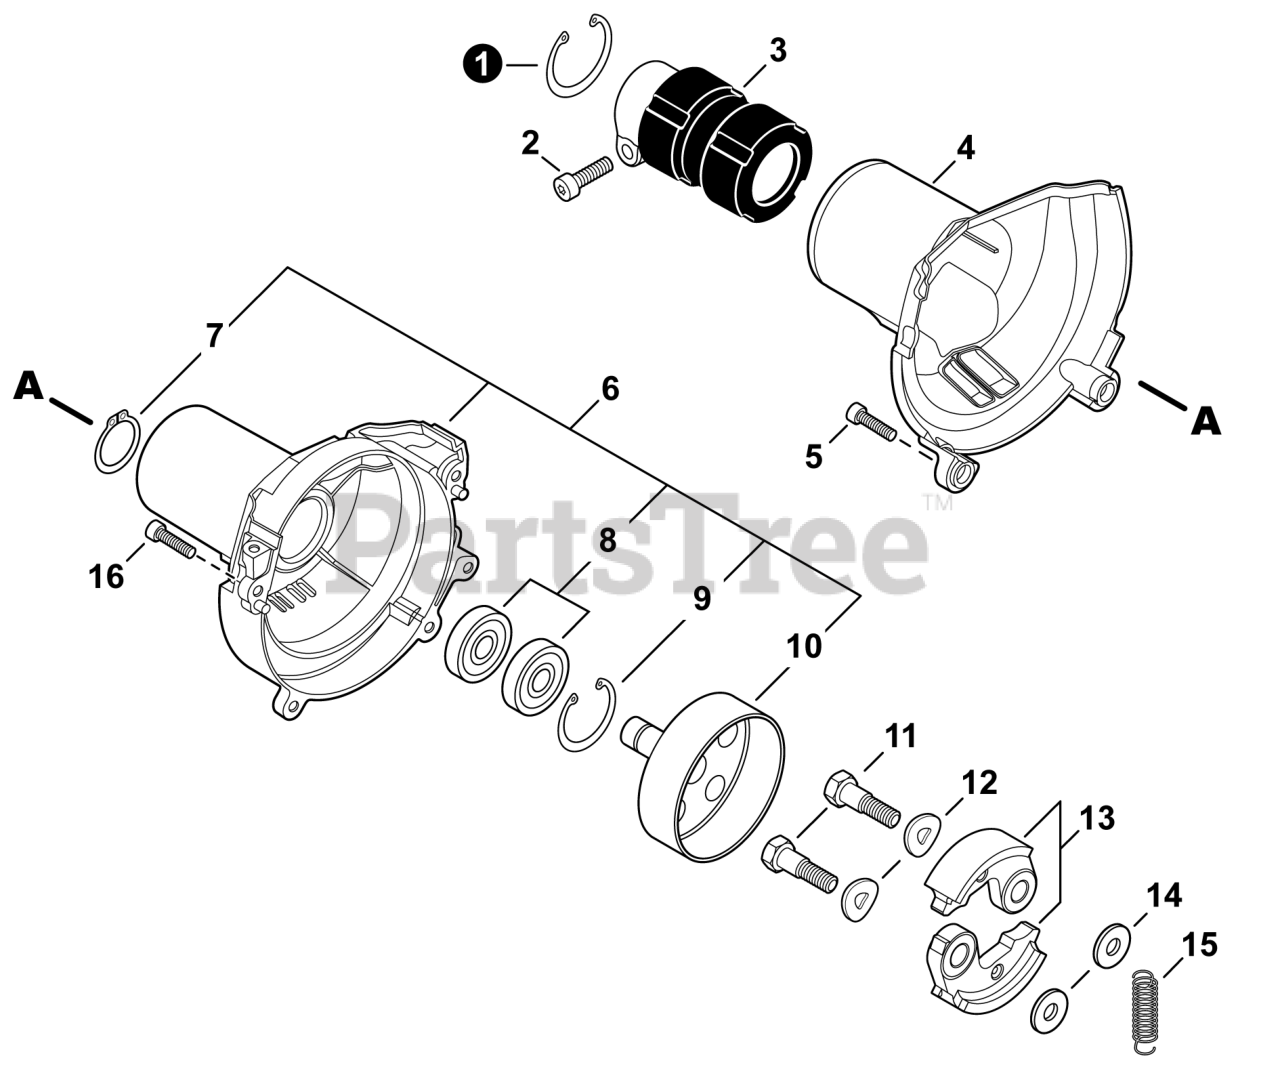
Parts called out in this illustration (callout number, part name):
1	RING, SNAP Ø42
2	BOLT, TORX 5×25
3	HOLDER, MAIN PIPE
4	PROTECTOR, FAN COVER
5	BOLT, TORX 5×20
6	COVER ASSY, FAN
7	RING, RETAINING 15
8	BEARING, BALL
9	RING, SNAP 28
10	DRUM, CLUTCH
11	BOLT, CLUTCH 8×7.9×M6
12	WASHER, SPRING 8.5×16×0.5
13	SHOE, CLUTCH
14	WASHER 6.2×19×1.0
15	SPRING, CLUTCH
16	BOLT, TORX 5×16
